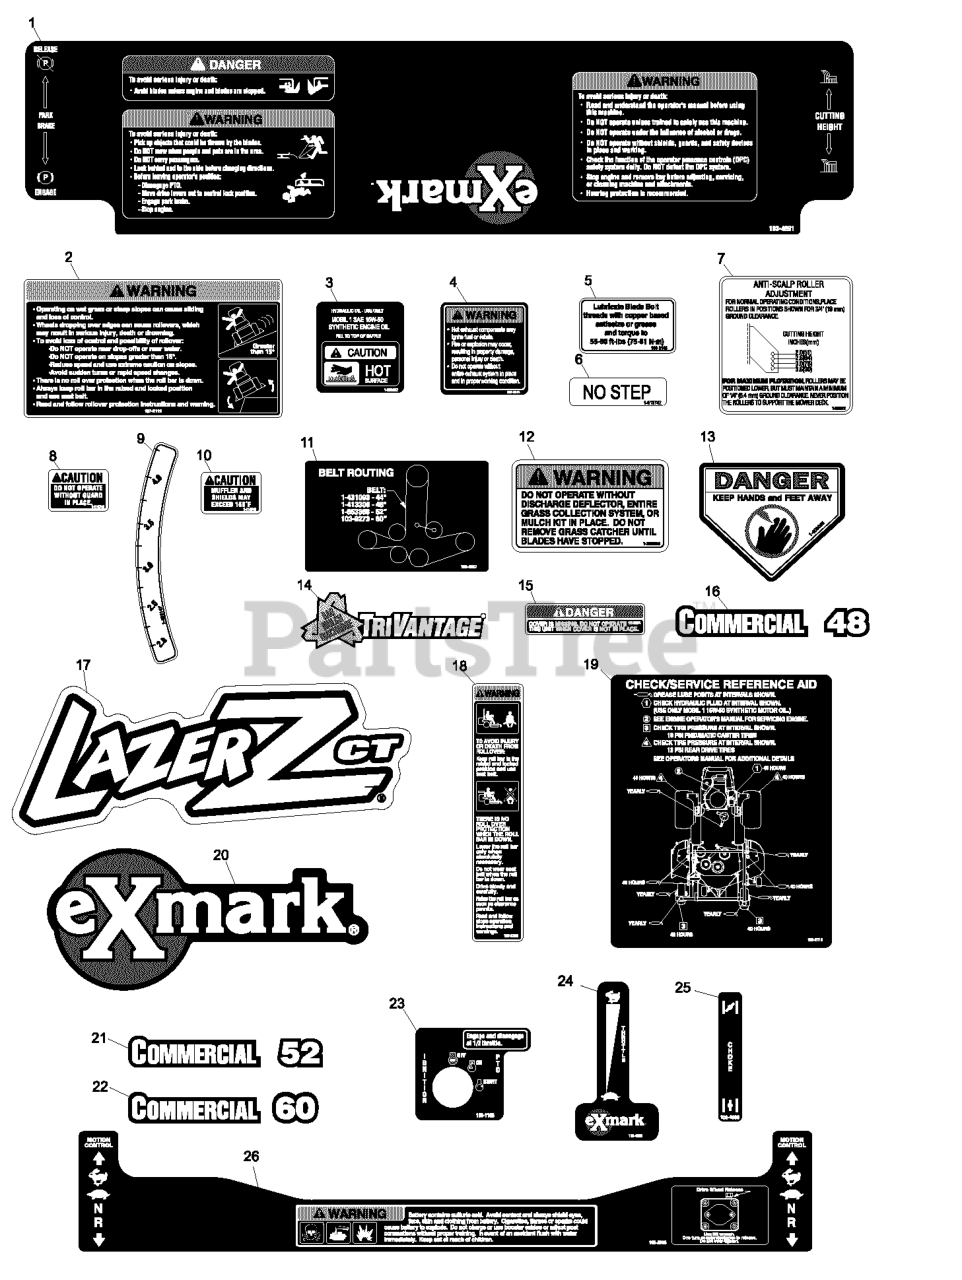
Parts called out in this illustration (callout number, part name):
1	DECAL,CONSOLE LHP
2	DECAL-WARNING
4	DECAL-EXHAUST
5	DECAL,BOLT TORQUE
6	DECAL,NO STEP
7	DECAL,ANTISCALP
8	DECAL-GUARD
9	DECAL-DECK HEIGHT, INNER
11	DECAL, BELT ROUTING
12	DECAL-WARNING, DISCHARGE
13	DECAL-DANGER
15	DECAL-COVER, MISSING
16	DECAL,COMMERCIAL 48
17	DECAL,LCT MODEL
18	DECAL-WARNING, FOLDING RO
19	DECAL, CHECK/SERVICE LCT
20	DECAL,EXMARK LOGO
21	DECAL,COMMERCIAL 52
22	DECAL,COMMERCIAL 60
23	DECAL,IGNITION/PTO
24	DECAL,THROTTLE
25	DECAL,CHOKE
26	DECAL-WARNING
26	KIT,DECAL LCT
